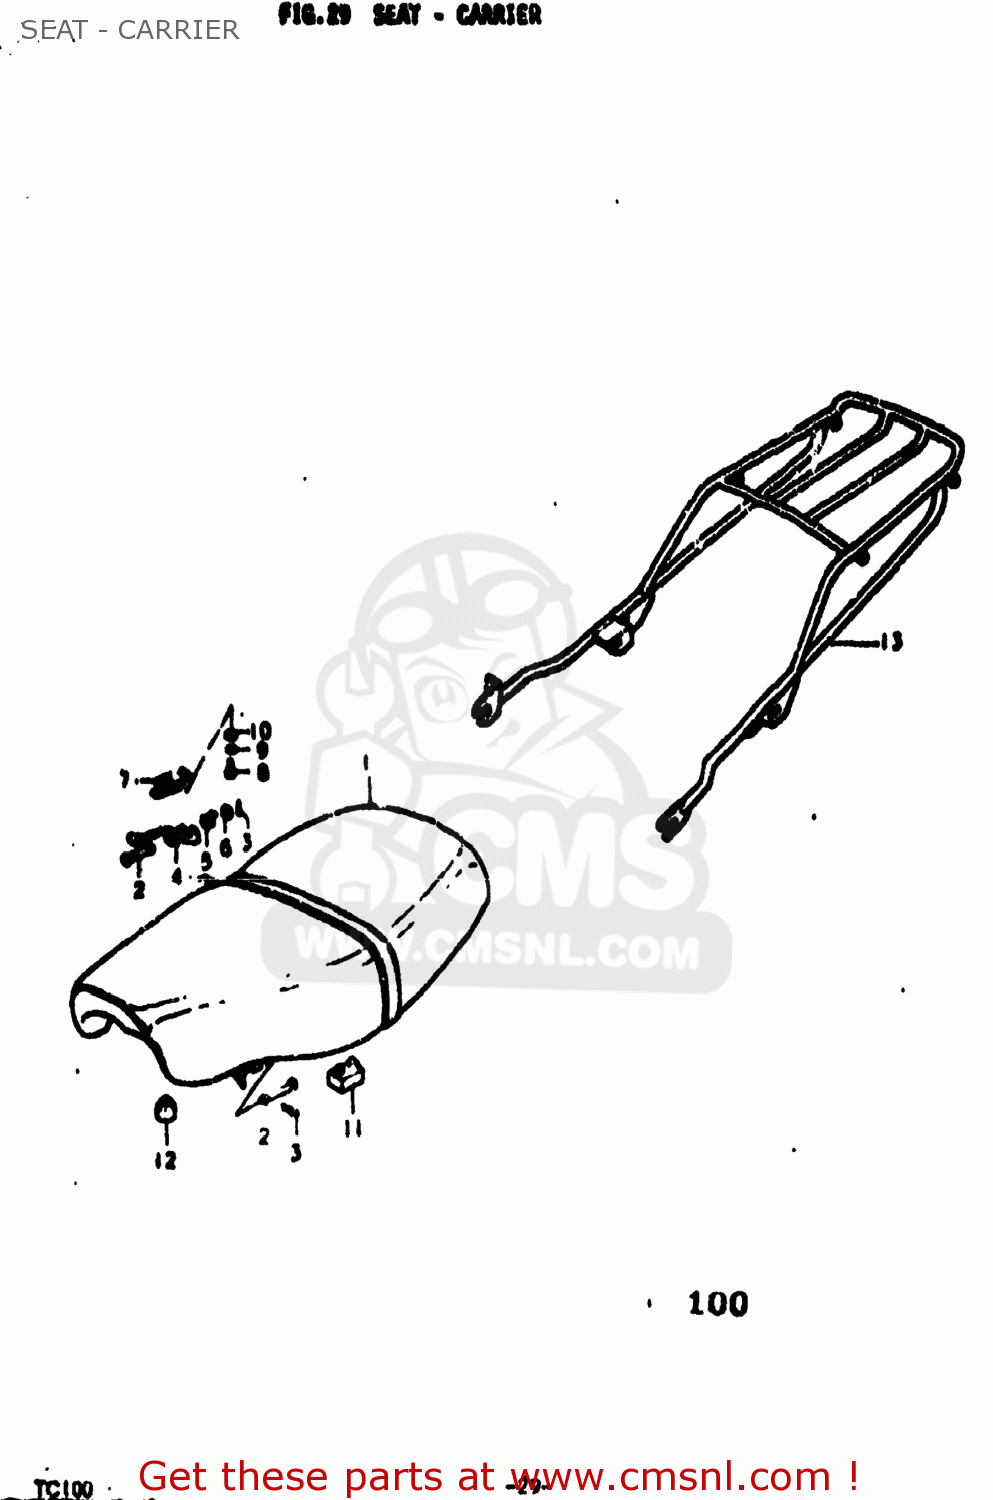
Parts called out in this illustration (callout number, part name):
1	SEAT ASSEMBLY
2	PIN
3	CLIP
4	STRIKER,SEAT LOCK
5	SPRING
6	WASHER
7	PLATE,SEAT CLAMP GUIDE
8	BOLT
9	LOCK WASHER
10	WASHER
11	CUSHION
12	CUSHION
13	CARRIER
